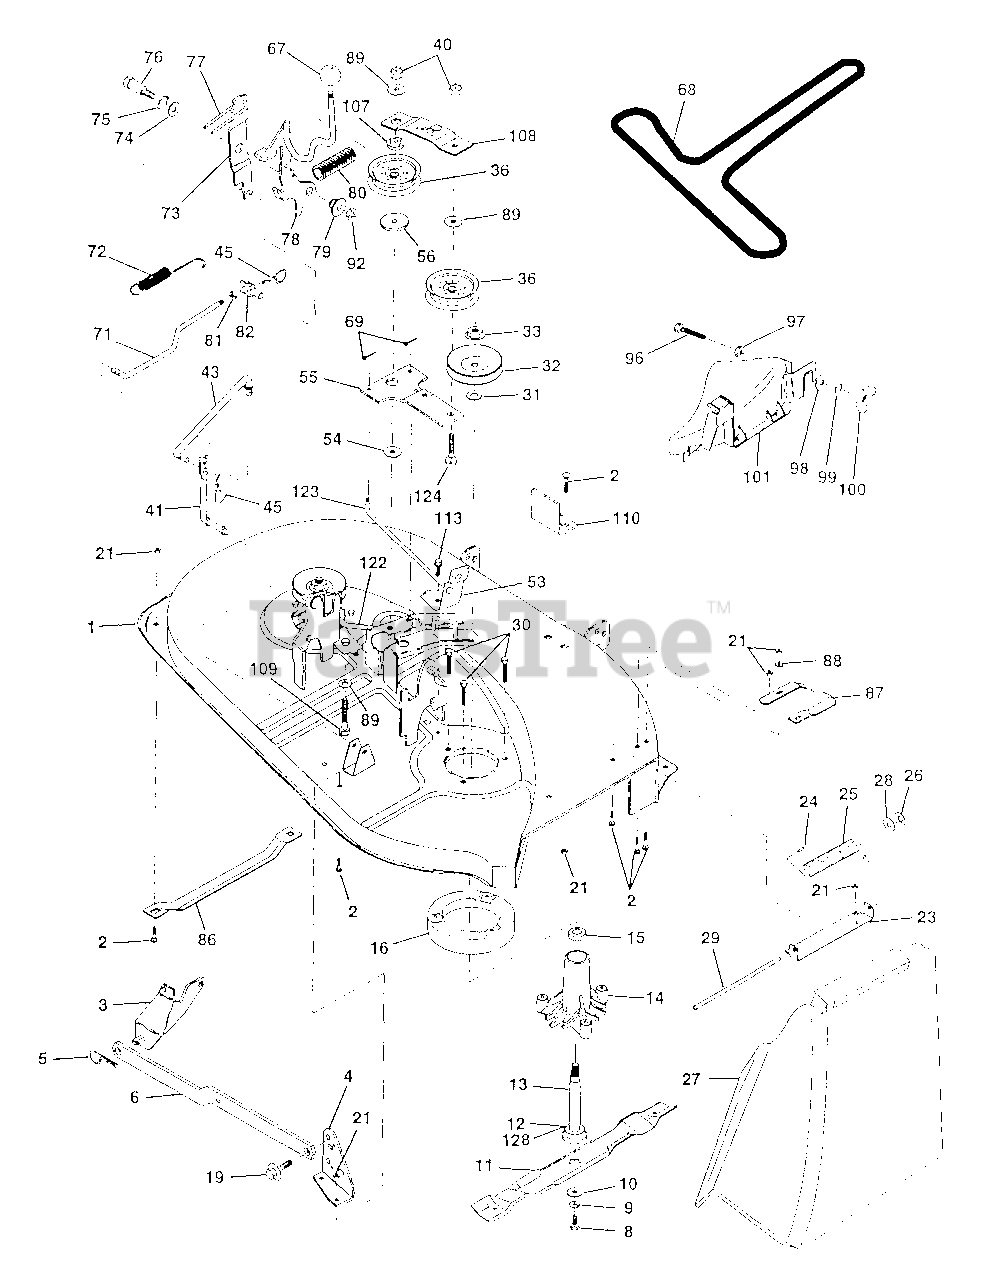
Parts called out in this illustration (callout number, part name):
1	Mower Asm 38" welded (AYP part number)
2	Bolt Rdhd Sqnk 5/16-18 unc X 3/4
3	Bracket assembly, front
4	Bracket assembly, decl
5	Retaining spring (AYP part number)
6	Arm, suspension rear (AYP part number)
8	Bolt 3/8-24 x 1 25 Gr 8 Patched
9	Washer Lock Hvy 3/8 Unplated (AYP part number)
10	Washer Hard Blade Mower Vented
11	Blade Mulching 38"
12	Bearing Ball #6204 (Mandrel)
13	Shaft Asm W/lower Bearing (AYP part number)
14	Housing Mandrel Vented (machd)
15	Bearing Ball Mandrel
16	Stripper MWR (AYP part number)
19	Bolt Shoulder
21	Nut Crownlock 5/16-18 Unc
23	Bracket Deflector Mower
24	Cap Sleeve 80 x 112 Blk Mower
25	Spring Deflector
26	Nut Push Phos & Oil
27	Shield Deflector Mower 38" blk (AYP part number)
28	Washer 11/32 X 5/8 X 16 Ga
29	Rod Hinge Brt/blk Zinc 9 88 Lg
30	Screw Thdrol Hex Head Zinc Mwr (AYP part number)
31	Washer Spacer Mower Vented (AYP part number)
32	Pulley Mandrel 38" (AYP part number)
33	Nut 9/16 top Lock Flng Cntr
36	Pulley Idler Flat 3 060 (AYP part number)
40	Nut Crownlock 3/8-16 Unc
41	Rod Pivot W/nibs
43	Rod Clutch Secondary W/nibs
45	Spring Retainer 1" Zinc/cad
53	Brake Asm Mower Vented
54	Washer Hardened (AYP part number)
55	Arm Idler 38"
56	Spacer Retainer Pm Mower
67	Knob Round
68	V-Belt Mower
69	Pin Cotter 3/32 X 3/4 Cad
71	Rod Clutch Primary 38/42
72	Spring Return
73	Arm Clutch Secondary
74	Washer 25/32 X 1-5/8 X 16 Ga
75	Ring Klip #t5304-75
76	Bolt Shoulder 3/8-16 Unc 1 44
77	Keeper Spring 4 000
78	Arm Asm Clutch Primary
79	Bushing 747 Od X 794 Lg Brass
80	Spring Clutch Mower
81	Nut Hex Jam 3/8-16
82	Trunnion Adj '94
86	Runner Mower LH 10 00
87	Runner RH 38"
88	Washer 11/32 X 3/4 X 16 Ga
89	Washer 13/32 X 1 X 12 Ga
92	Nut Lock Hex W/ins. 3/8-16 UNC
96	Bolt 3/8-16 x 1-1/4 Mulcher
97	Nut Centerlock 3/8-16 UNC
98	Washer 13/32 x 1-1/4 x 16 Ga. (AYP part number)
99	Washer Lock Hvy Hlcl Spr. 3/8
100	Nut Wing
101	Cover Asm Mulcher 38"
107	Spacer Arm Idler Upper Hdn 42"
108	Stiffener Arm Idler Upper 42"
109	Bolt Hex Fin 3/8-16 x 2-1/2
110	Upstop Deck front
113	Screw Thdrol 5/16-18 X 3/4 TYT
122	Rod Brake Mandrel LH 4 856
123	Rod Brake Mandrel RH 10 744
124	Bolt Rdhd 3/8-16 unc x 1-3/4 Gr 5
128	Washer Felt
